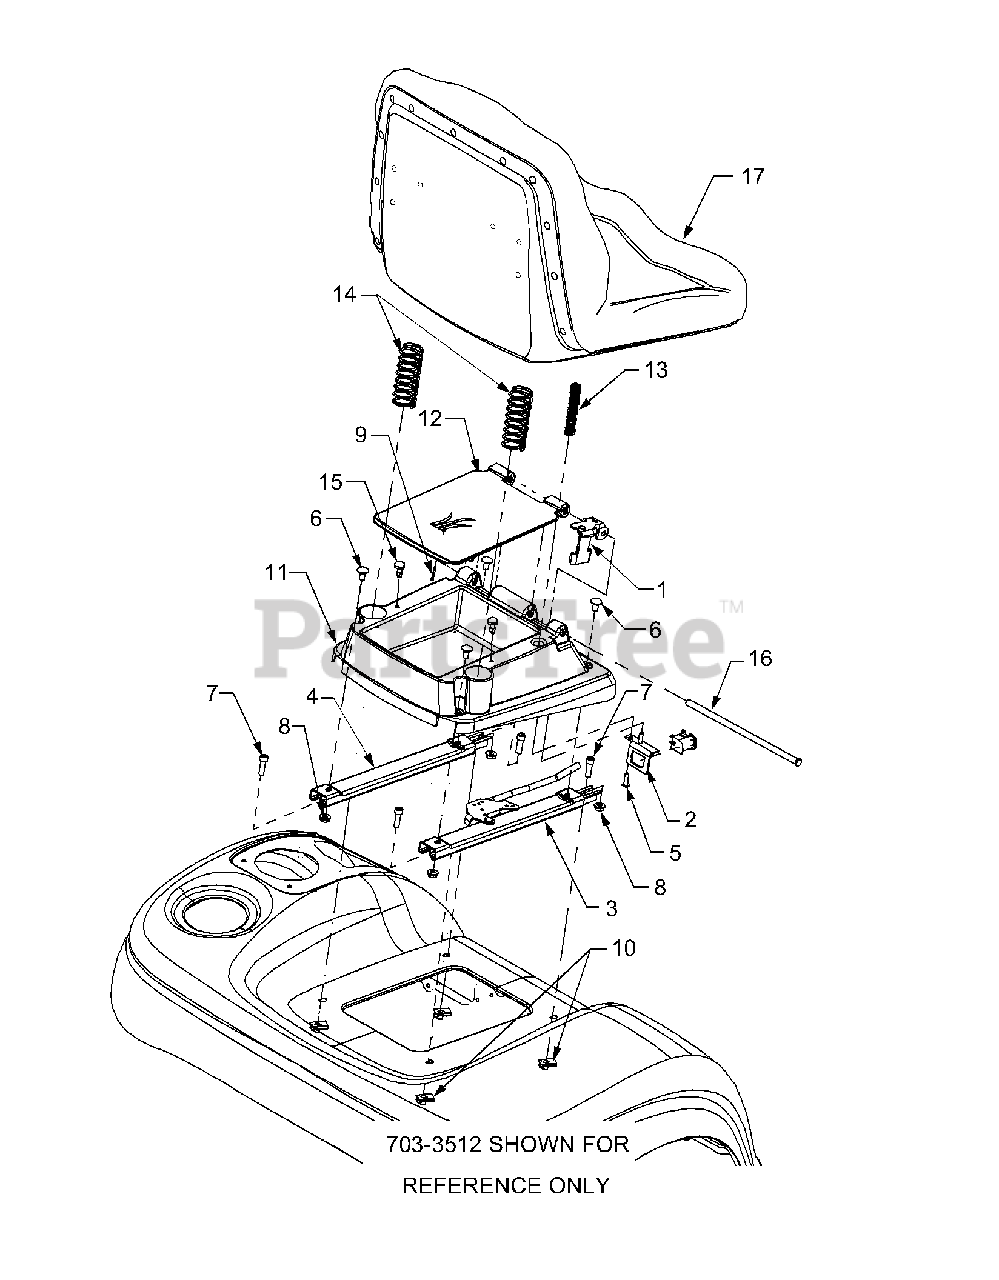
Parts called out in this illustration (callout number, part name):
1	Bracket, Seat Switch
2	Bracket, Switch Mounting
3	Track, Seat, w/Latch
4	Track, Seat, w/o Latch
5	Screw, Pan Torx Hd., #12-14 x .5
6	Carriage Bolt, 5/16-18 x .62
7	Screw, Pan Torx Hd 5/16-18 x 1.0
8	Nut, Hex Flange Lock, 5/16-18
9	Pin, Cotter, 3/32 x .75
10	Speed Nut, U-Type, 5/16-18
11	Base, Seat
12	Lid, Tlbx
13	Spring, Compression
14	Spring, Compression
15	Bumper
16	Rod, Seat Pivot
17	Seat, High Back
